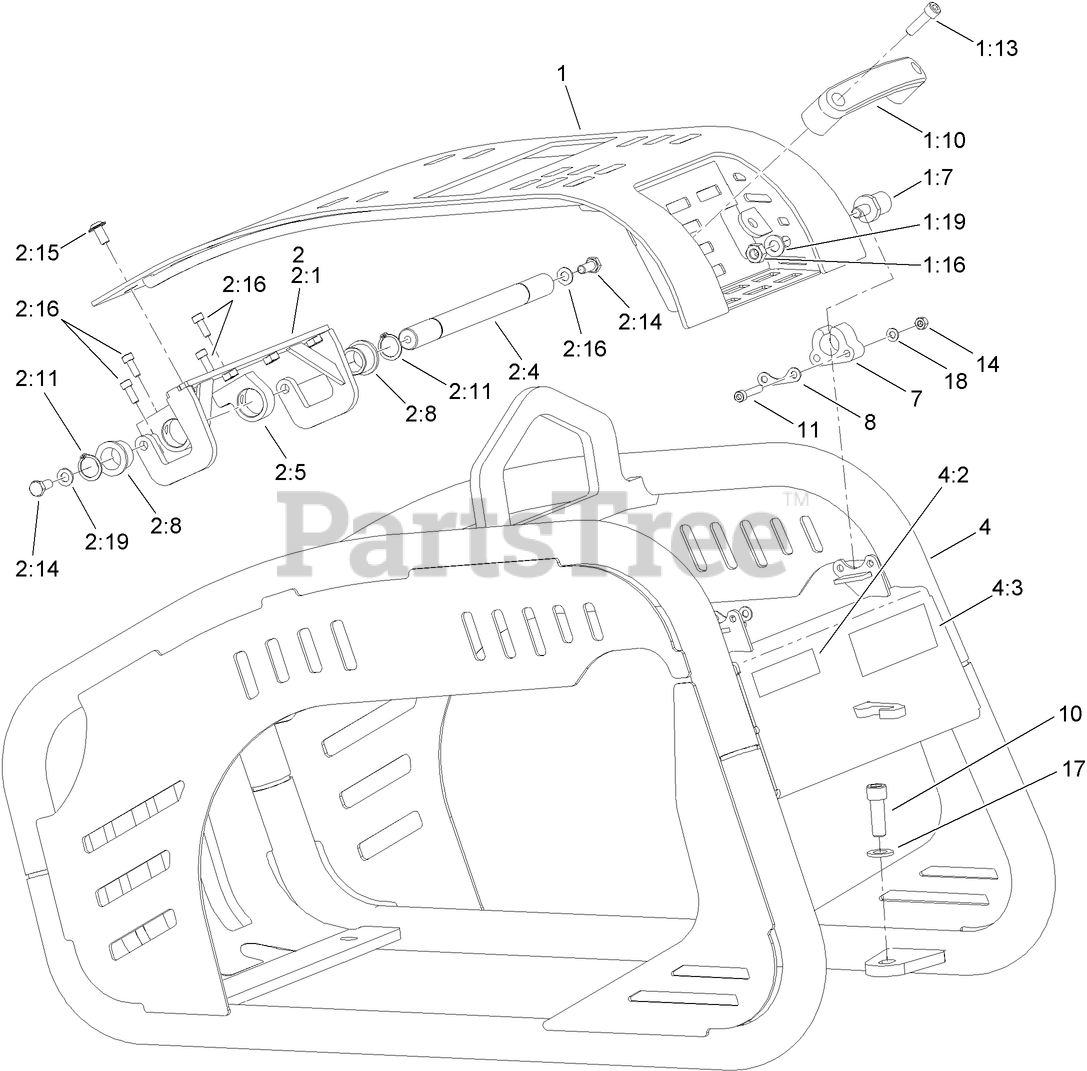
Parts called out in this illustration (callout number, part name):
1	TOP COVER ASM
1:7	PIN-HANDLE
1:10	HANDLE
1:16	NUT-LOCK, NI
1:19	WASHER
2	COVER ASM
2:1	BRACKET-FRONT
2:8	BUSHING
2:11	RING-SEALING
2:19	WASHER
4	FRAME ASM
4:2	DECAL-ARRESTER, SPARK
4:3	DECAL-WARNING, PLATE
7	SECURING-COVER
8	WASHER-SECURING
17	WASHER
18	WASHER
